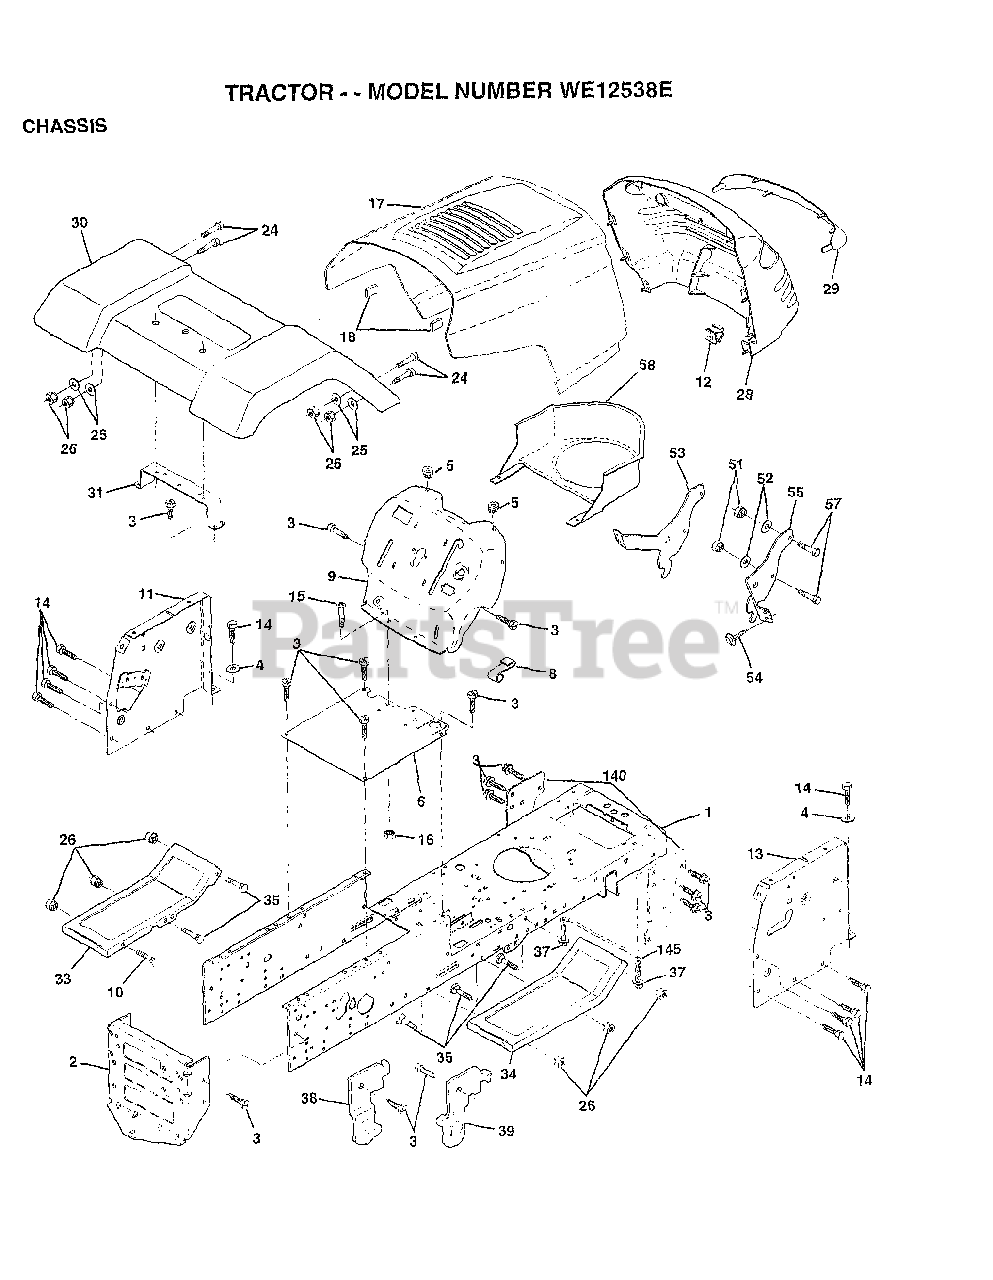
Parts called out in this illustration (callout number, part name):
1	CHASSIS ASM
3	SCREW
4	WASHER
5	BUMPER-HOOD/DASH
6	"SADDLE-SLKSCR,5SP"
8	CLIP.RETAINER
9	DASH.SILKSCREENED
11	"PANEL-DASH,LH"
12	CLIP.TINNERMAN
14	SCREW LT
15	SCREW
17	HOOD.STEEL.ASSY
24	BOLT
25	WASHER
26	NUT
28	GRILLE-MS428
29	LENS GRILLE
31	BRKT FENDER
33	FOOTREST.LH.PERF.
34	FOOTREST.RH.PERF.
35	BOLT
37	SCREW LT
38	BRACKET ASM LH
39	BRACKET ASM RH
51	NUT
52	WASHER
53	BRACKET.GRILLE.LH
55	BRACKET.GRILLE.RH
57	BOLT
58	AIR DUCT
140	BRKT SUSPENSION
145	"ROD POVOT,CHASSIS"
